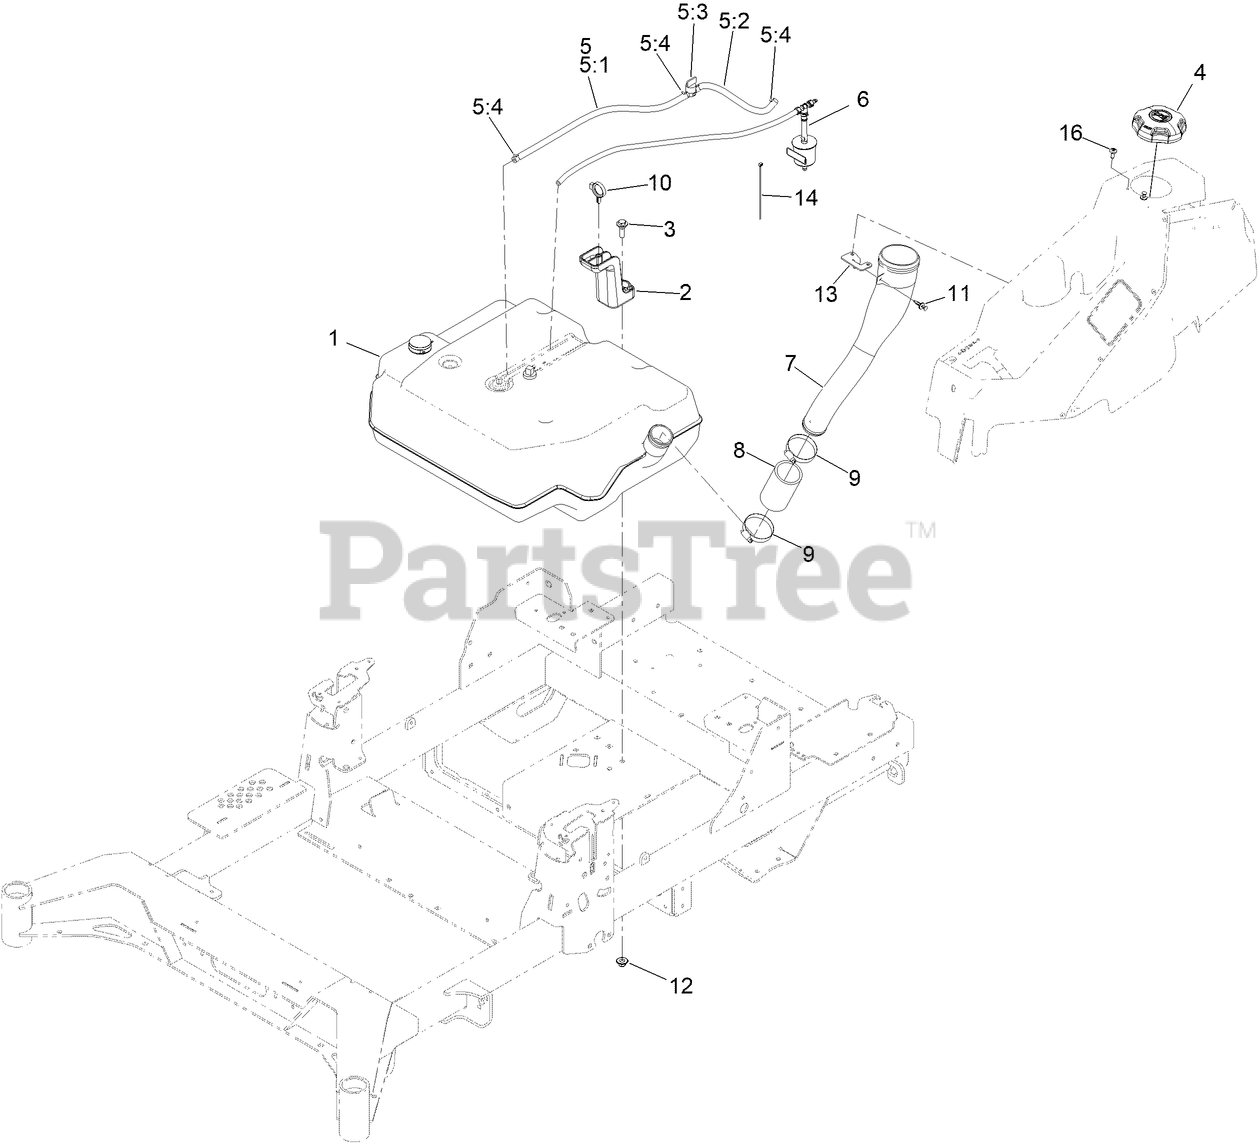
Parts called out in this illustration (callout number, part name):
1	TANK ASM-FUEL
2	RETAINER-TANK, REAR
3	SCREW-SHOULDER, HWH
4	CAP-FUEL, RATCHETING
5	FUEL HOSE ASM
5:1	HOSE-FUEL
5:2	HOSE-FUEL
5:3	VALVE-FUEL
5:4	CLAMP-HOSE
6	VENT HOSE ASM
7	NECK-FILLER, FUEL
8	HOSE-FILLER, FUEL
9	CLAMP-HOSE
10	CLAMP-HOSE
11	RIVET-BLIND
12	NUT-HF, NI
13	BRACKET-MOUNTING, FILL
14	CLIP-EDGE W/TIE, PERPENDICULAR
16	SCREW-SHOULDER
